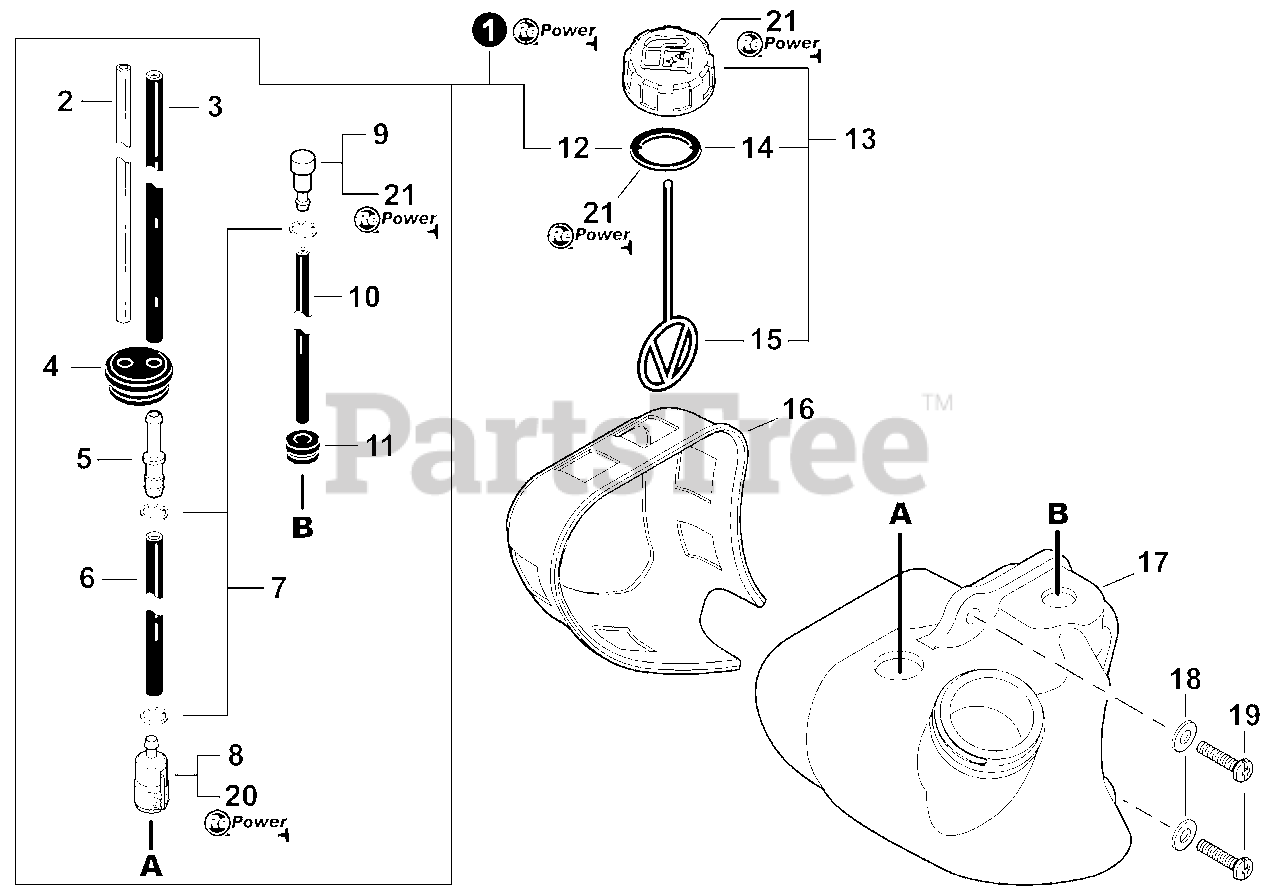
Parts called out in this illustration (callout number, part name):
1	FUEL SYSTEM KIT
2	PIPE, FUEL 3×6×85 CLEAR
3	PIPE, FUEL 3×5×87 BLACK
4	GROMMET, FUEL
5	CONNECTOR, PIPE Ø5ר3.5
6	PIPE, FUEL 3×5×90 BLACK
7	CLIP Ø6
8	FILTER, FUEL
9	VENT ASSY
10	PIPE, FUEL VENT 3×5×50
11	GROMMET
12	GASKET, FUEL CAP
13	CAP ASSY, FUEL
14	GASKET, FUEL CAP
15	CONNECTOR, CAP L= 100 MM
16	GUARD, FUEL TANK
17	TANK, FUEL
18	WASHER 5.5×12×0.8
19	SCREW, TAPPING 5×20
20	TUNE-UP KIT - REPOWER
21	CAP/VENT KIT - REPOWER
